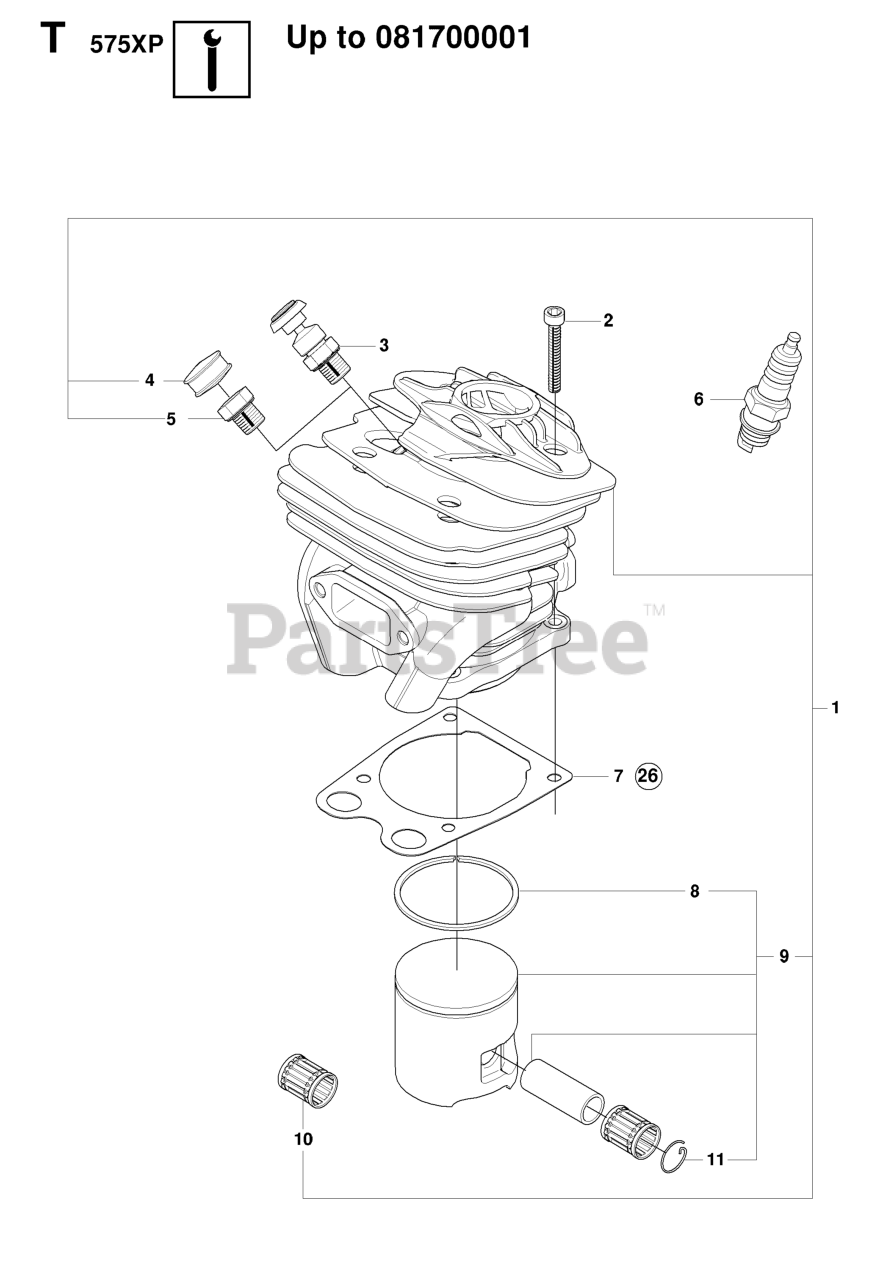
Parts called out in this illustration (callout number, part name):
1	%CYLINDER
2	SCREW MC6S 5X25
3	VALVE
5	CYLINDER PLUG
6	SPARK PLUG M14X1.25 NGK BPMR7A
8	PISTON RING
9	PISTON 49 MM
10	SUPPORT BUSHING
11	WRIST PIN CLIP
26	GASKET SET
